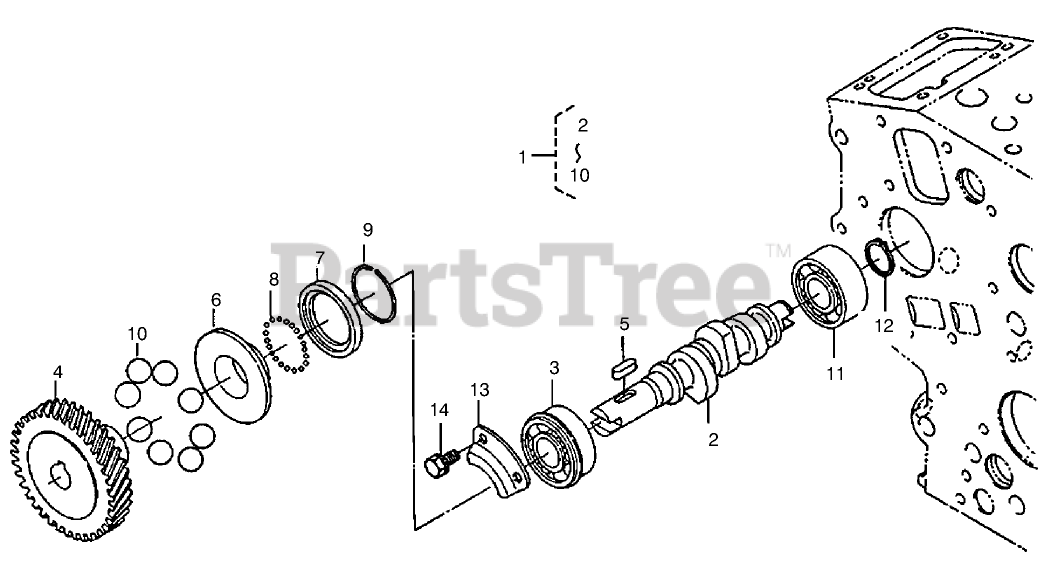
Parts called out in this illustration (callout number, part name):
1	FUEL CAMSHAFT ASM
2	CAMSHAFT
3	BEARING-BALL
4	GEAR-PUMP, INJECTION
5	KEY-FEATHER
6	SLEEVE-GOVERNOR
7	CASE-BALL, GOVERNOR
9	CIRC-CLIP
11	BEARING-BALL
12	CIRC-CLIP, EXTERNAL
13	STOPPER-FUEL, CAMSHAFT
